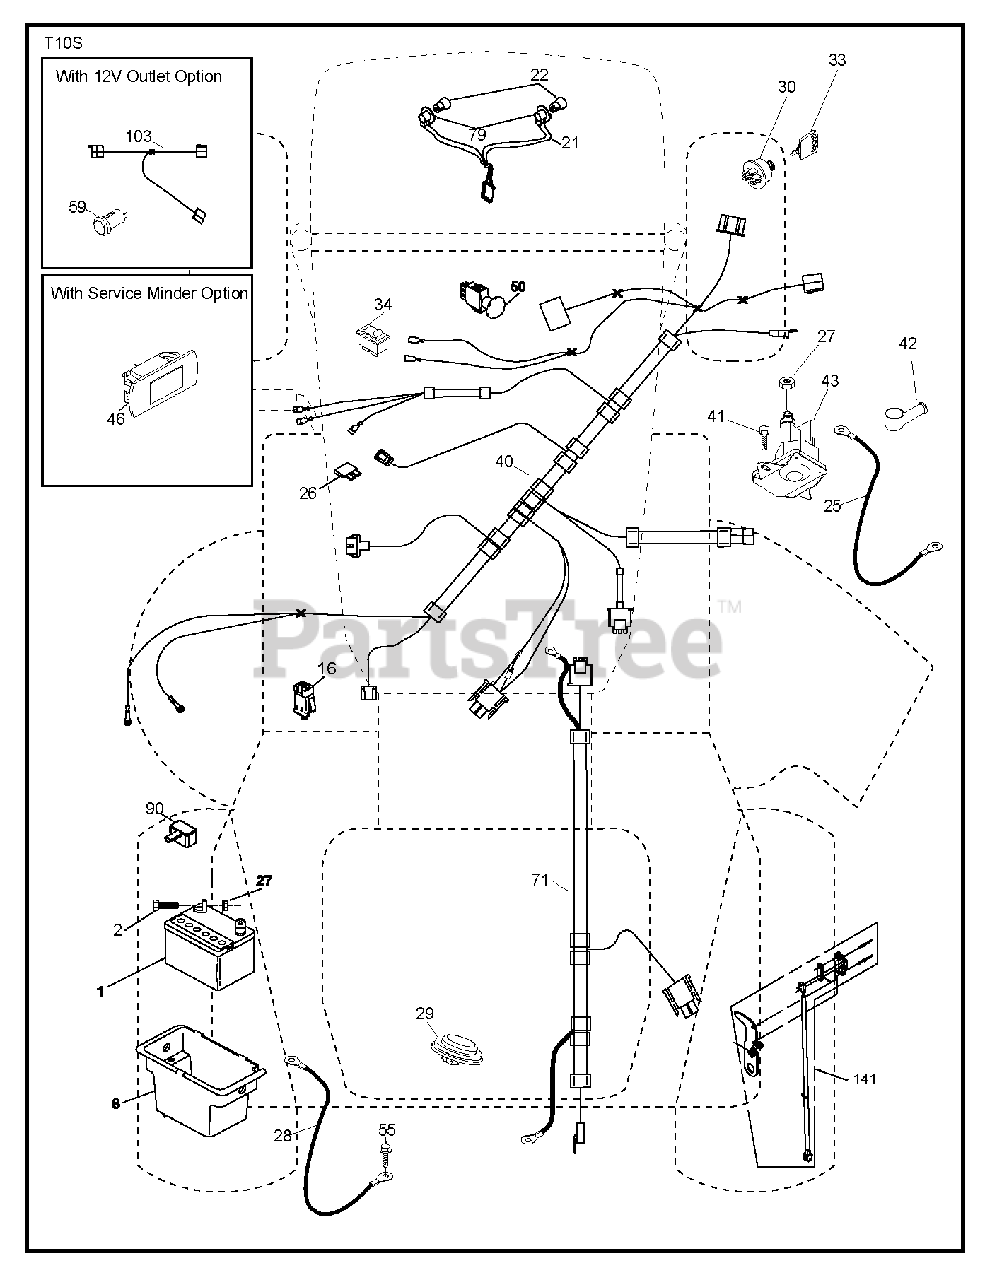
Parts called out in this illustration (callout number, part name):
1	Battery, Dry 30 Amp
2	BOLT.HEX.1/4.X.3/4.DICHROMATE
8	BOX.BATTERY.MNT.REAR.L
16	SWITCH INTERLOOK PUSH-IN
21	HARNESS.LIGHT W/4152J BULBS
25	CABLE.STARTER.6GA.BL/RED.14.
26	FUSE 20AMP
27	NUT
28	CABLE.BLACK.18"REAR.BA
29	SWITCH.SEAT.DELTA.OPC.
30	SWITCH.IGN.DELTA.W.LGH.ROS
33	KEY.CHAIN.BLISTER.PACK.GEN.INT
40	HARNESS.IGN.DASH.HUQ/P
41	SCREW
42	TERMINAL COVER
43	SOLENOID.W/BRASS.PLUNGER
46	RP GUAGE.SRVCMNDR.HRMTR.
50	RB PTO.SWITCH.8 TERMINAL.BLACK
55	SCREW 5/16"
71	HARNESS.CHASSIS.TEX.8AWG
79	BULB HOLDER ASM.
90	COVER.TERMINAL.BATTERY
141	KIT T2.ROS 71677
